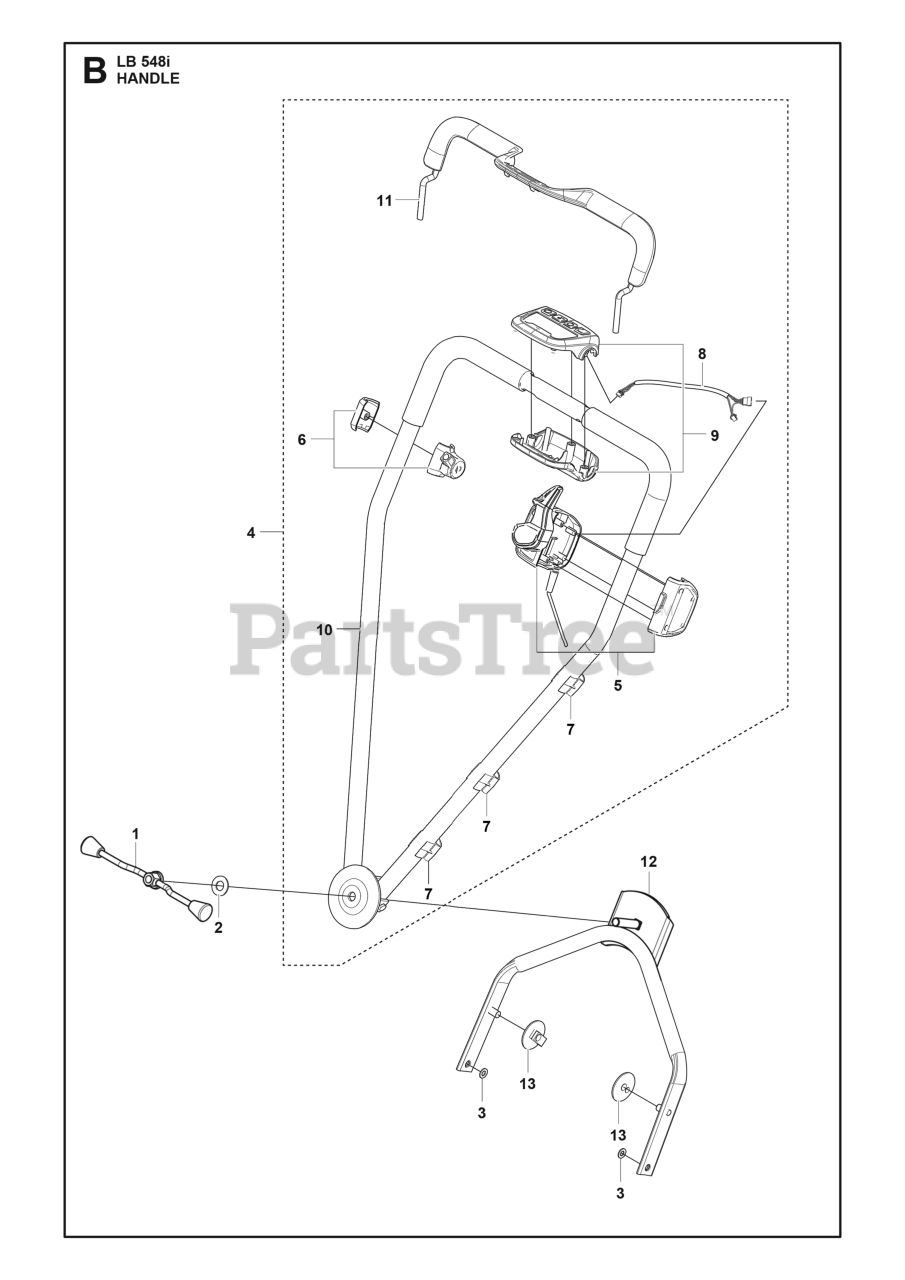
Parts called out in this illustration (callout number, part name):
3	RETAINING RING SGA 10
5	SWITCHBOX ASSY ASSY LC247LI
6	BAIL ARM ASSY SPARE PART ASSY
7	CABLE HOLDER HANDLE ASSY
8	EXTENSION CABLE CONTROL PANEL
